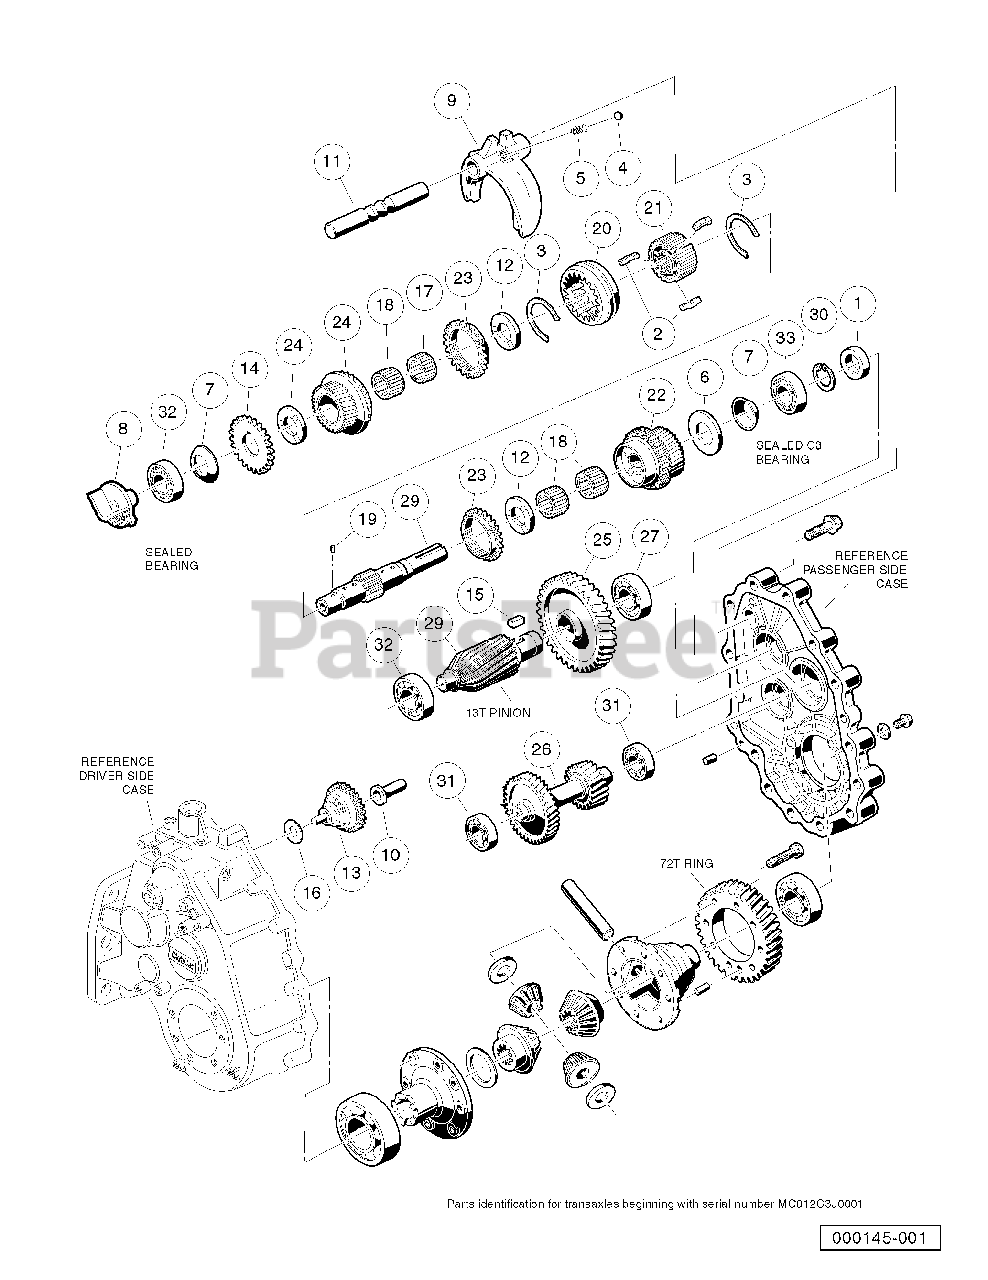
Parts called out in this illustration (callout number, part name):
2	Synchro Insert
3	Synchro Spring
4	Shifter Ball
5	Shifter Spring
6	Washer, Thrust
7	Washer, Spring
9	Fork - Shift
10	Sleeve, Governor
11	Rod, Shift
12	Plate, Thrust
13	Governor Assembly
14	Gear, Spur
17	Needle Bearing
18	Needle Bearing
19	Pin, .116" Dia X 0.264 Dowel
20	Sleeve, Synchro
21	Hub, Synchro Clutch
22	Gear Assembly, 16-Degree Synchro
23	Ring, 16-Degree Synchronizer
24	Gear Assembly Input 25-Tooth
25	Gear, 70-Tooth
26	Gear Cluster Idler
27	Bearing, Ball
28	Gear, Helical, 13-Tooth
29	Shaft, Trans, with Circlip
32	Bearing, Ball, Sealed
33	Bearing, Ball, Sealed
